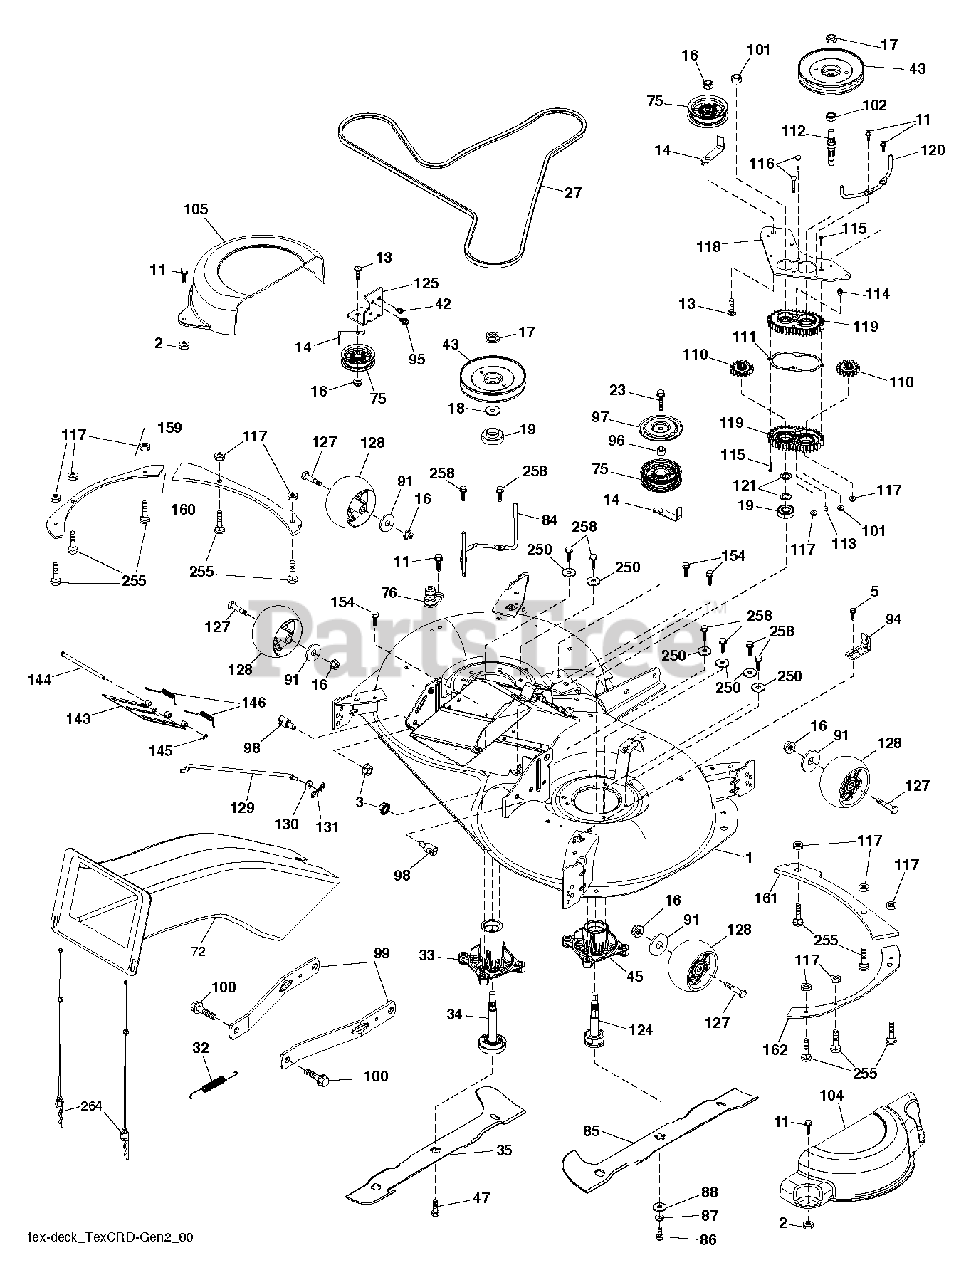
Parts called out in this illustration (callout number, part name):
1	DECK SVC 107HP.EZMUL.498
2	PALNUT 1/4
3	NUT LOCK HEX FLANGE 5/16-18
5	BOLT.5/16HEX.WHS.HD
11	SCREW.1/4-20X5/8
13	BOLT.3/8-16X1.50
14	KEEPER, BELT IDLER
16	NUT LOCK FLG 3/8-16 UNC
17	NUT.FLANGE.LOCK.TOP
18	WASHER.SPACER.MANDREL
19	BEARING.MANDREL.TOP.EXTENDED
23	SCREW LT
27	BELT.ELECT.MOWER.DRIVE 97.8 EL
32	SPRING 107CM & 97CM ELECTRIC D
33	HOUSING.MANDREL.REV.TALL.N/GRS
34	SHAFT ASM.REV.TALL.N/GREASEBL
35	BLADE.107.LH.SINGLE.NON.QD
42	SCREW
43	PULLEY PULLEY MANDREL 5.438 PD
45	RP HOUSING.MANDREL.REV.REVS.
47	SCREW.SEMS.7/16-20X1.HEX.HEAD
72	RB CHUTE 107/97 TEX GENII
75	FLAT IDLER PULLEY
76	PORT.WASHOUT
84	KEEPER KEEPER. LH MANDREL BELT
85	BLADE.107.RH.SINGLE.NON.QD
86	BOLT.3/8-24X1.25GR8. LHTHRD
87	LOCKWASHER
88	WASHER.BLADE
91	WASHER
94	BRKT.CLUTCH.CABLE
95	SCREW, 3/8-16X3/4
96	SPACER
97	PROTECTOR
98	STUD.FASTNER.W/ANTI-ROTATE
99	ARM.SUSPENSION.MOWER.R
100	BOLT.SHOULDER
101	NUT.CROWNLOCK.9/16 -18.UNC
102	SPACER BEARING
104	COVER.MANDREL.107.RH.GEN.2
105	COVER.MANDREL.107.LH.GEN.2
110	CRD.SPUR.GEAR
111	GASKET GASKET GEARCASE
112	SHAFT SHAFT. CRD GEARCASE ADAP
113	PLUG PLUG OIL
114	VENT.BREATHER.1/8 NPT
115	SCREW
116	BOLT.CARIGE.SS.1/4-20X1.75GR5
117	NUT T
118	ARM ARM. CLUTCHING 107 TEX CRD
119	GEARCASE GEARCASE SUBASM
120	KEEPER KEEPER. RH MANDREL BELT
121	WASHER WASHER
124	SUB.ASM.REVERSE.THREAD.REV
125	BRACKET BRACKET IDLER CHASSES
127	BOLT.SHOULDER.3/8-16X3-5/8.
128	WHEEL. GUAGE RALLY
129	ROD ROD. SWAY CRD GEN II
130	WASHER
131	PIN.COTTER.5/16.BOW TI
143	COVER DOOR.107 CM CRD EZ MULCH
144	PIN PIN.HINGE
145	E-RING.5/16"
146	SPRING SPRING: EZ MULCH DOOR
154	SCREW T-30 1/4-20 X
159	REINFORCE.PLATE.LH.FT.X431
160	REINFORCE.PLATE.LHS.BOLT.431
161	REINFORCE.PLATE.RH.FRT.X431
162	REINFORCE.PLAT.RH.SD.BLT.X431
255	RHSNB, 1/4-20 X 1, GR5
258	BOLT.HEX.WASHR.HED.313-18X1.19
264	RETAINER.ASM.UPPERCHU
